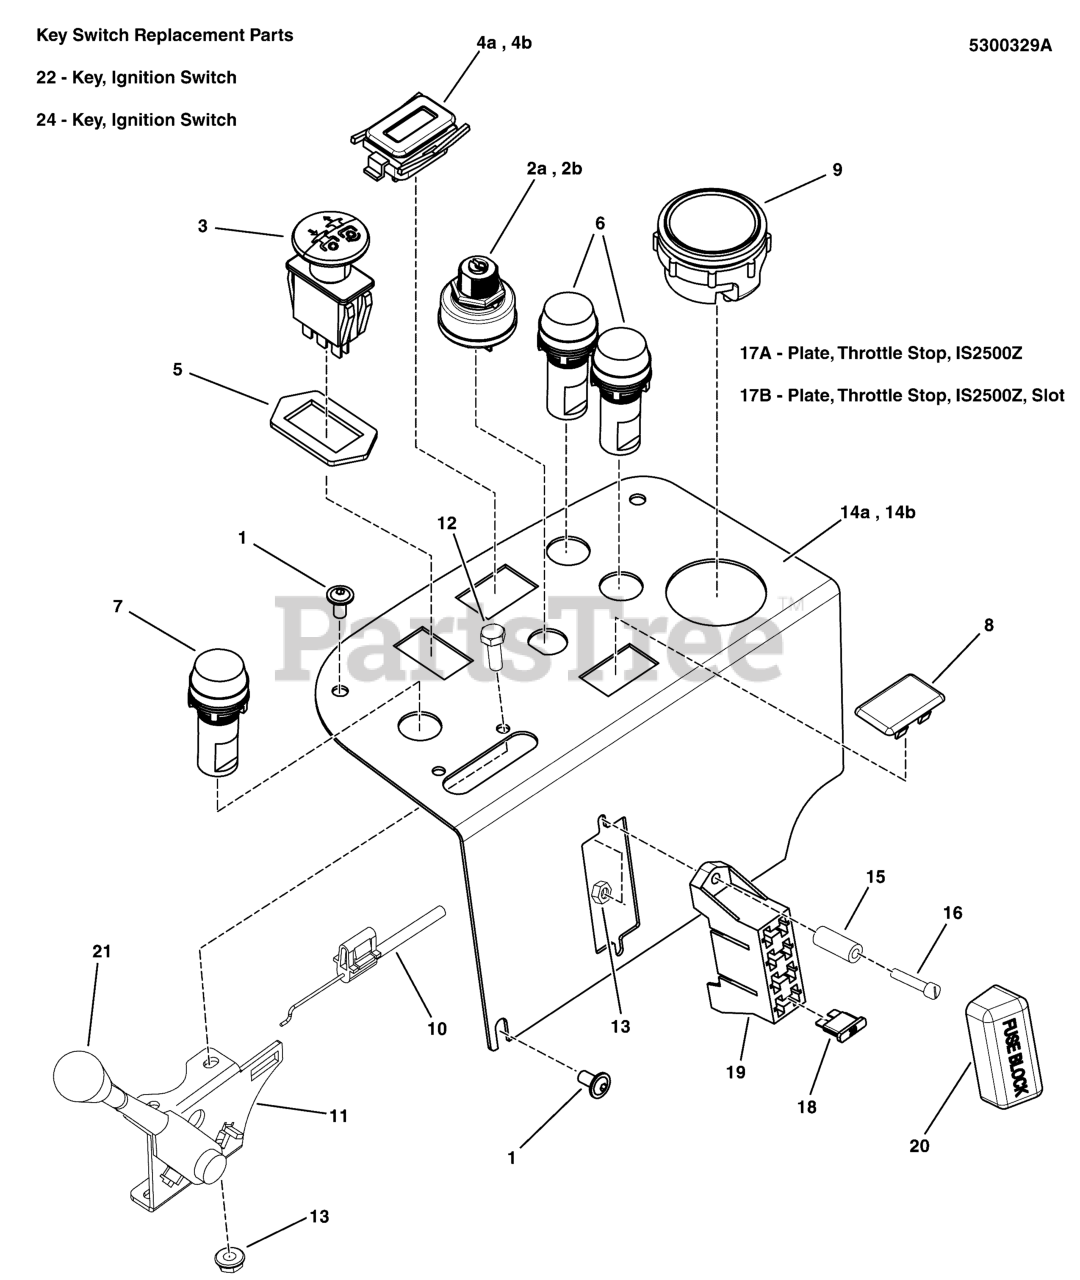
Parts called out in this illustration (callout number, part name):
1	SCREW, 1/4-20 X 1/2 ALLEN BH
3	SWITCH, BLADE ENGAGEMENT
5	RING, SWITCH RETAINER
6	LIGHT, WARNING, 22MM RED
7	LIGHT, GLOW PLUG, 22MM AMBER
8	PLUG, .820X1.44 HOLE, BLACK PLASTIC
9	GAUGE, WATER TEMPERATURE
10	CABLE, THROTTLE, 52"
11	LEVER, THROTTLE CONTROL, HEAVY-DUTY
12	SCREW, #10-24 X 3/4 ROUND PHILLIPS
13	NUT, #10-24 HEX NYLON LOCK
15	SPACER, .20 X .38 X 1.75, YZ
16	SCREW, 10-24 X 2-1/2, RD HD PHILLIPS, CZ
17A	PLATE, THROTTLE STOP - BLK
17B	PLATE, THROTTLE STOP, IS2500, SLOT
18	FUSE, ATO, 20 AMP
19	FUSE BLOCK
20	COVER, VINYL FUSEBLOCK
21	THROTTLE CONTROL HANDLE/KNOB
22	KEY SET, Ignition Switch, 3 position (SV)
24	KEY SET, INDAK IGNITION SWITCH, 4 POS (SV)
